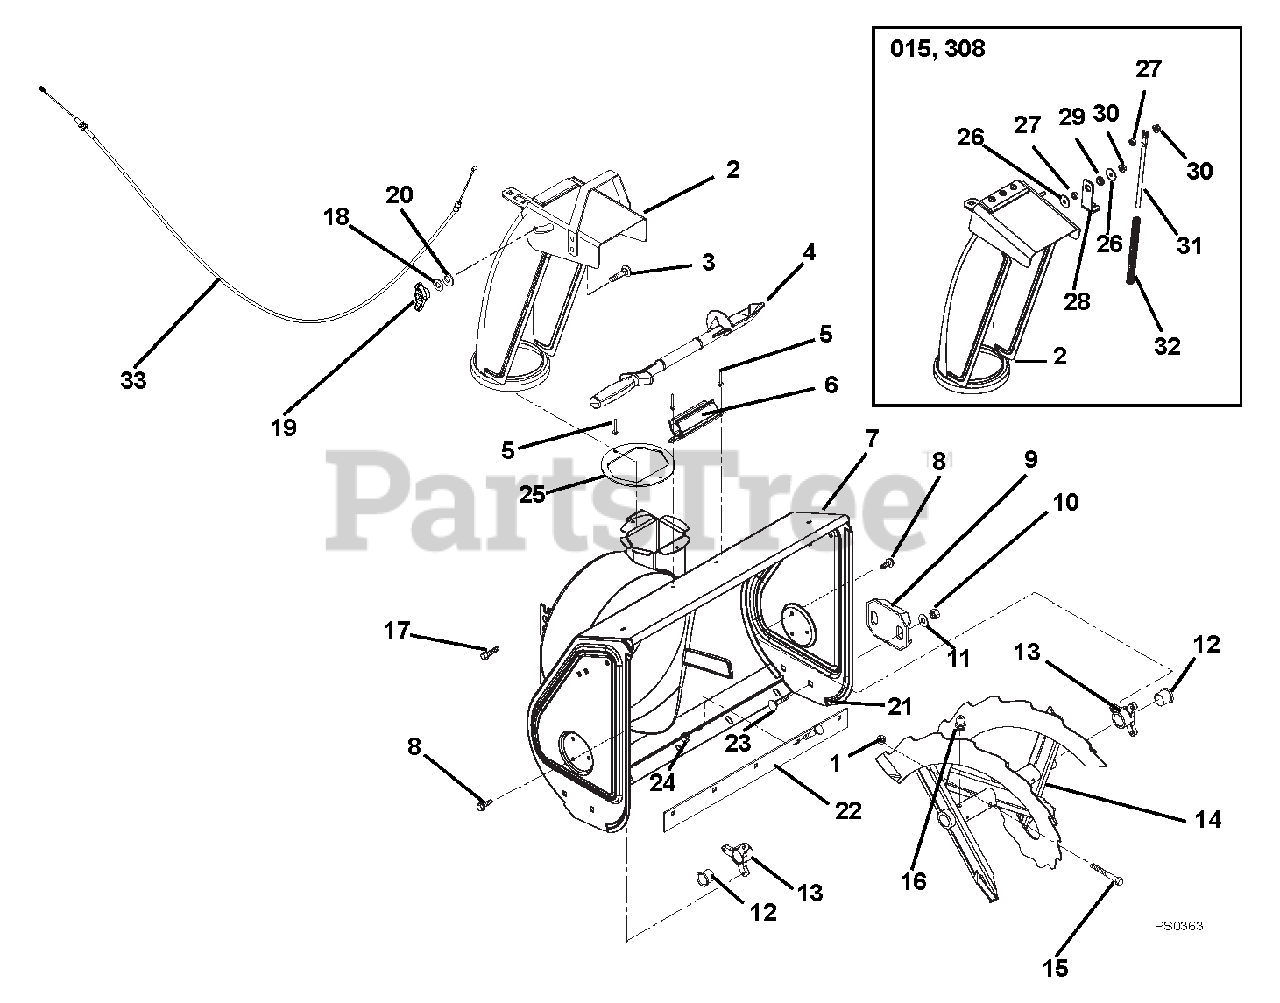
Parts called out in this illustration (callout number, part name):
1	@NUT-LK-CTR .25-20 YWZC
2	CHUTE, DISCHARGE W/CAP & DECAL
2	CHUTE, DISCHARGE W/REM.CAP,DEC
3	@BLT-RHDSSQNK .31-18X1.00 G5YZ
4	DEVICE, SNOW CLEAN OUT
5	RVT-POP .187 YZ
6	MOUNT, SNOW CLEAN OUT
7	BLOWER HOUSING - 20"
7	BLOWER HOUSING, 22" HI ORANGE
7	BLOWER HOUSING, 24" HI ORANGE
7	BLOWER HOUSING, 26" HI ORANGE
8	SCR-TAP .25-20X.50 HWH TR YWZ
9	SKID SHOE, REVERSIBLE - ORANGE
10	@NUT-LK-CTR .38-16 YWZC
11	@WSHR-FL-STL.38X.875X.083 YWZC
12	BSHG-FLG SPLIT NYLINER .75"ID
13	BUSHING, RAKE SHAFT .75"
14	RAKE, 24" RH, BLK SERR W/ZERK
14	AUGER, 20" RH, BLK SERR W/ZERK
14	RAKE, 24" LH, BLK SERR W/ZERK
14	AUGER, LH 20", BLK SERR W/ZERK
15	SHEAR BOLT WITH NUT
16	ZERK,FITTING .25X.125 DRIVE IN
17	@SCR-TAP .31-18X.50 HWH TR YWZ
18	@WSHR-FL-STL.344X.688X.065YWZC
19	KNOB,WING .31-18 UNC NYL/TALC
20	WSHR-FL-NY .375X.75X.060
21	BLT,RDSHHDSQSHNK .31-18X.62 YZ
22	BLADE, SCRAPER - 20" COMPACT
22	SCRAPER BLADE, 22" COMPACT
22	SCRAPER BLADE, 24" COMPACT HI
22	SCRAPER BLADE, 26" COMPACT HI
23	@BLT-RHDSSQNK .38-16X.75 G5YZ
24	@NUT-LK-TOP-FLG .31-18 YWZC
25	BAFFLE, COMPACT DISCHARGE
26	WSHR-FL-STL .281X1.000X.063
27	BSHG-SLV .265X.500X.219
28	BRACKET, CABLE ANCHOR
29	BUSHING, POLYLINER-.50 SNAPIN
30	@NUT-LK-TOP-FLG .25-20 YWZC
31	ROD, DEFLECTOR CAP
32	SG-COMP .08X.40X6.50 14#/IN
33	CABLE, DEFLECTOR-COMPACT
